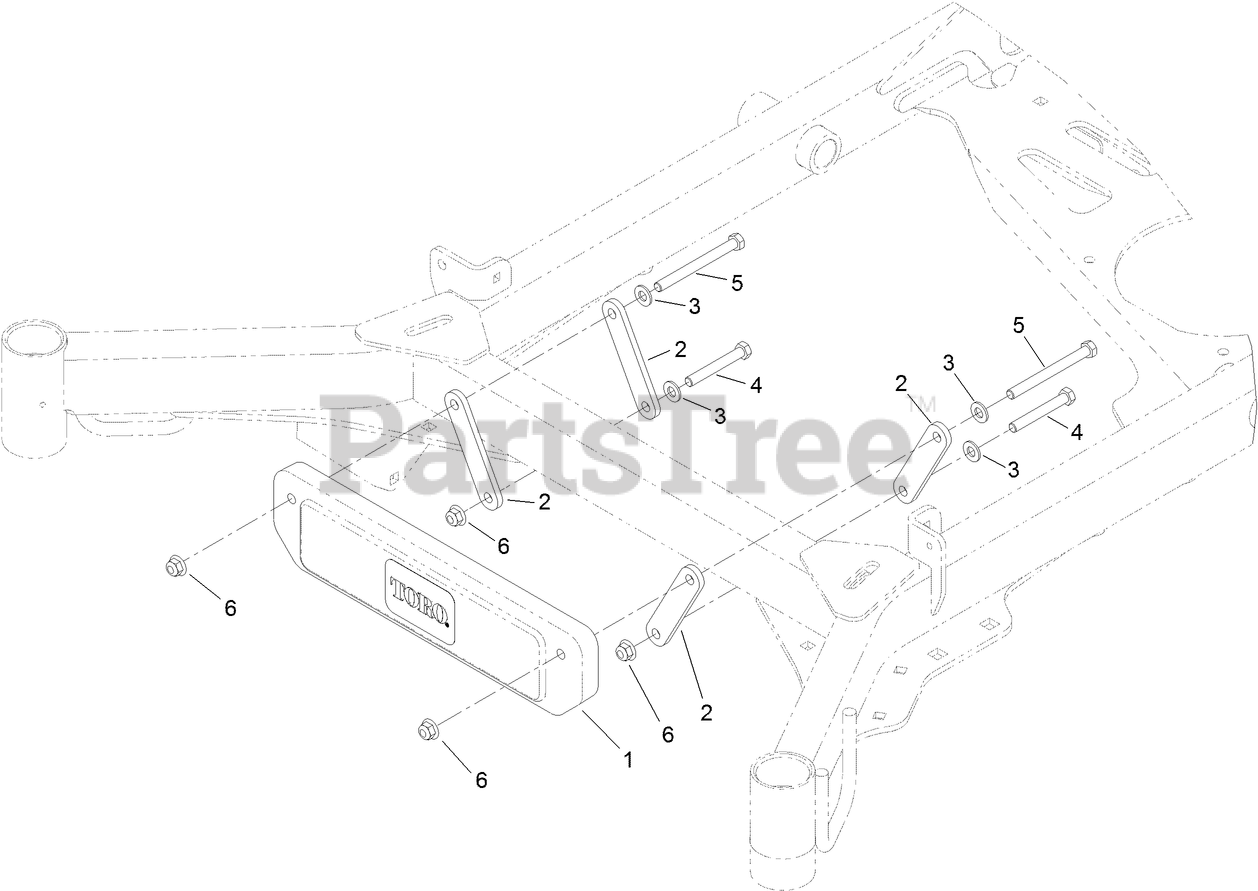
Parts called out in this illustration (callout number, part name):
1	WEIGHT-CAST
2	SPACER-WEIGHT
3	WASHER-FLAT
4	SCREW-HH
5	SCREW-HH (3/8 x 16 x 4 in)
5	SCREW-HH (3/8 x 16 x 5 in)
5	BOLT-TAP, HH (3/8 x 16 x 6 in)
6	NUT-HF, NI
